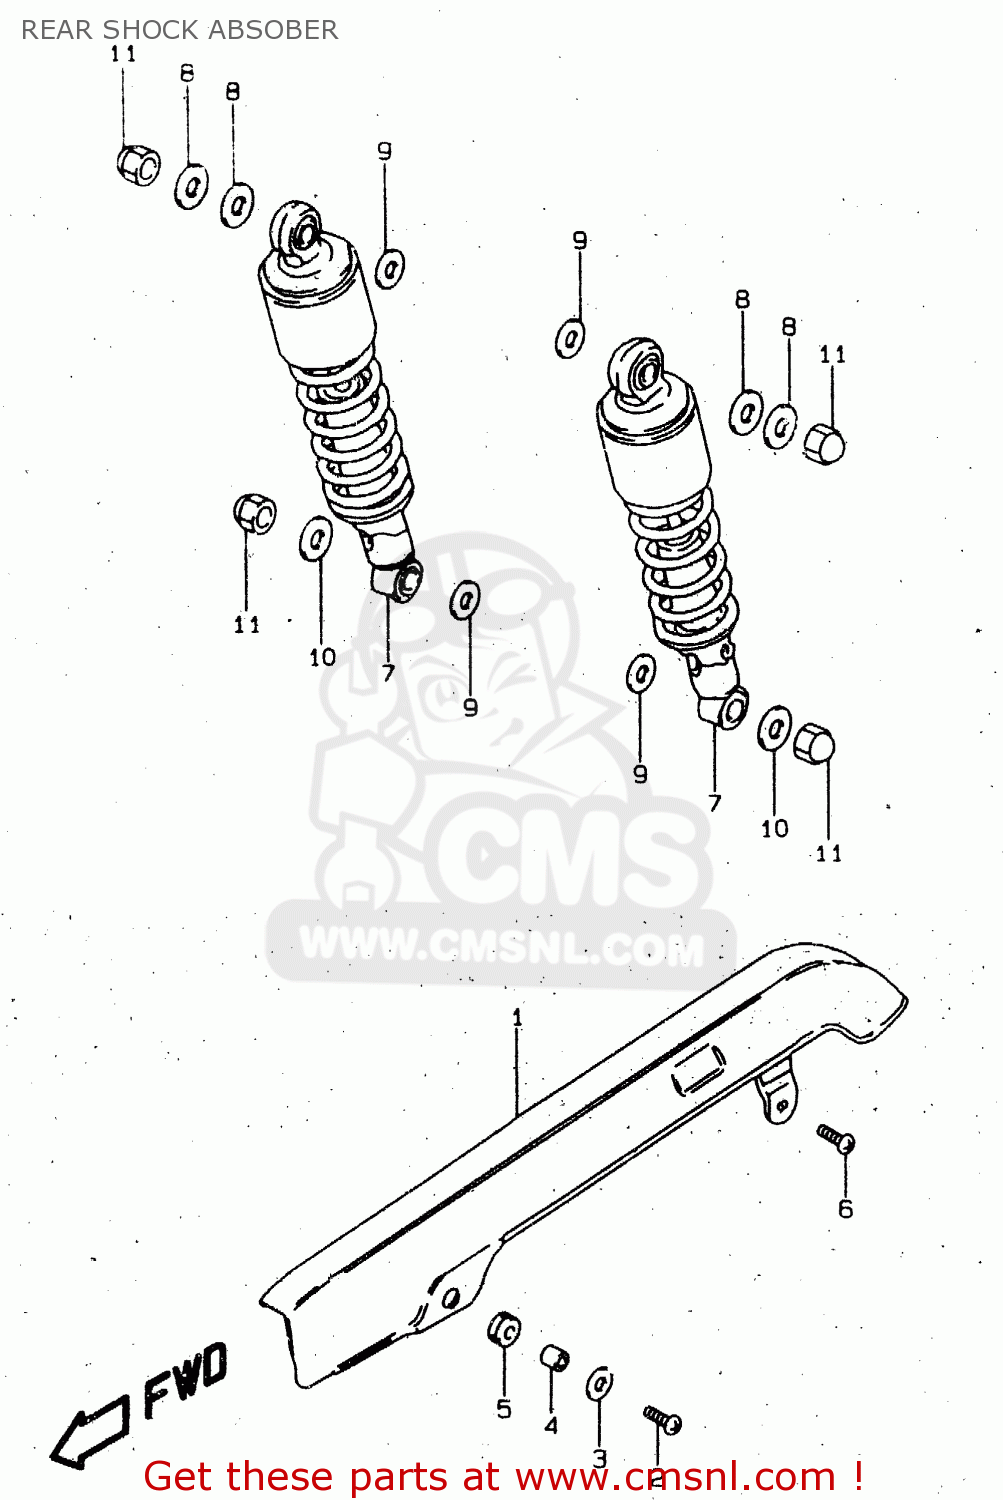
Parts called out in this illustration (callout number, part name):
1	CASE,CHAIN
2	SCREW
3	WASHER(6.5X20X1.2)
4	SPACER(6.5X9X7)
5	CUSHION
6	SCREW
7	ABSORBER ASSY,RR SHOCK
8	WASHER (10.5X24X2.3)
9	WASHER (12.5X26X1.6)
10	WASHER (10.5X24X2.3)
11	NUT
